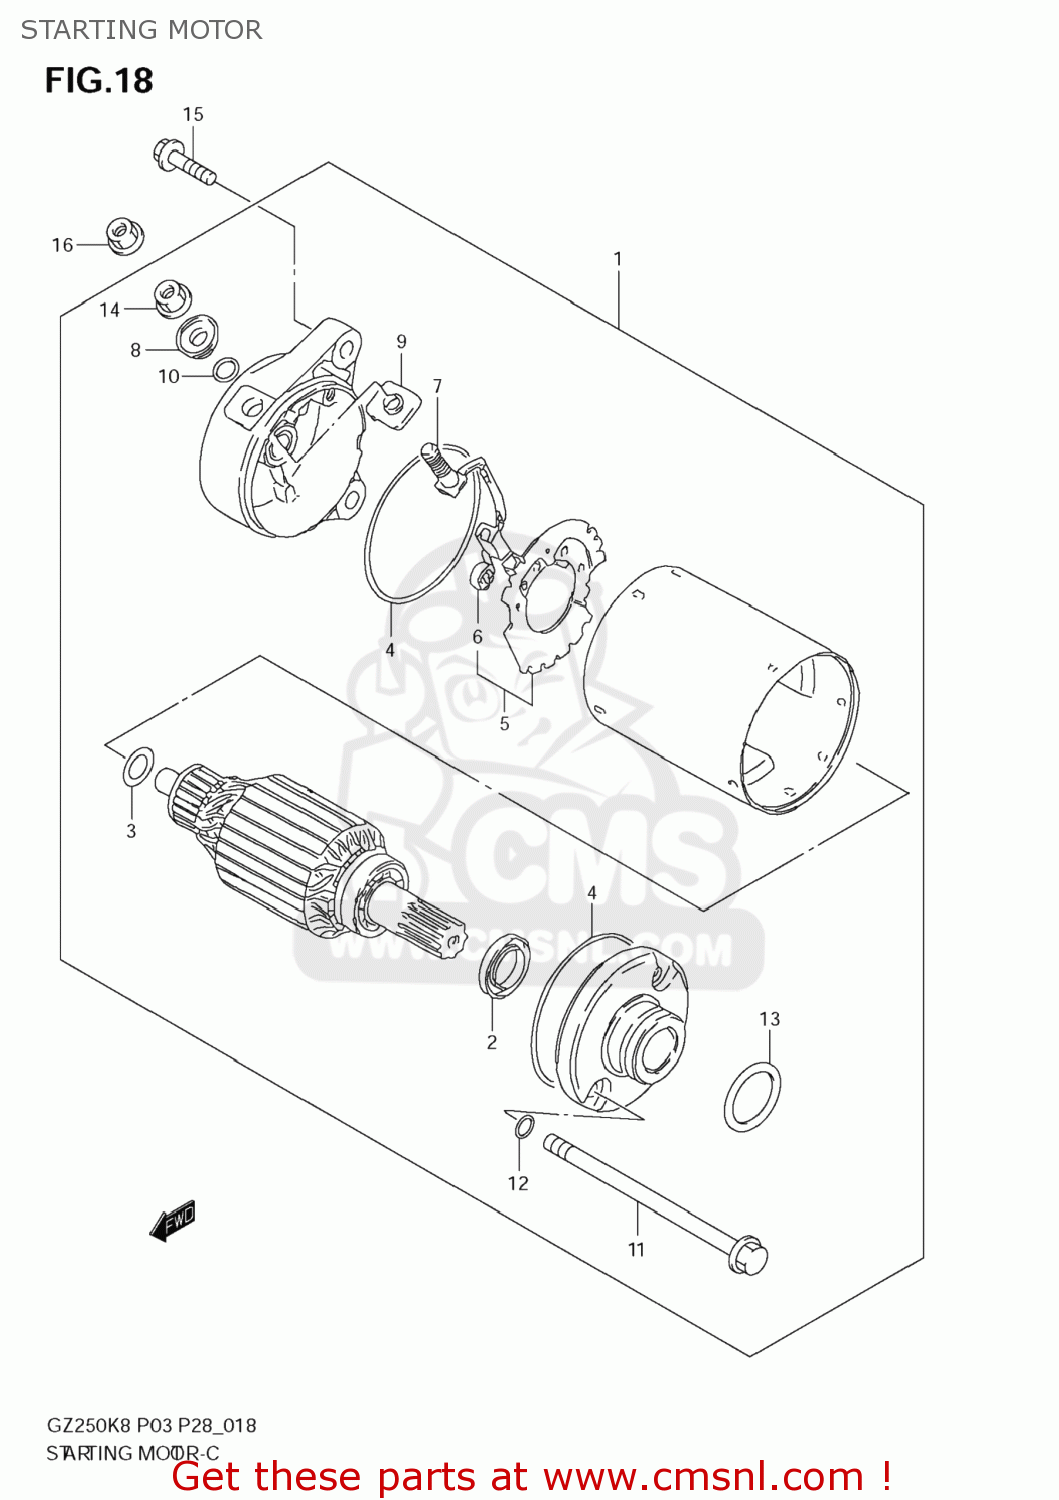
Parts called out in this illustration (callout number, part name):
1	MOTOR ASSY,STARTING
2	SEAL,OIL
3	SHIM SET,STARTING MOTOR
4	O RING
5	HOLDER,BRUSH
6	SPRING
7	BRUSH SUB ASSY,STARTING MOTOR
8	BUSHING
9	BUSH,B
10	O RING
11	BOLT
12	O RING
13	O RING(D:3,ID:24.5)
14	NUT
15	BOLT(6X25)
16	NUT
